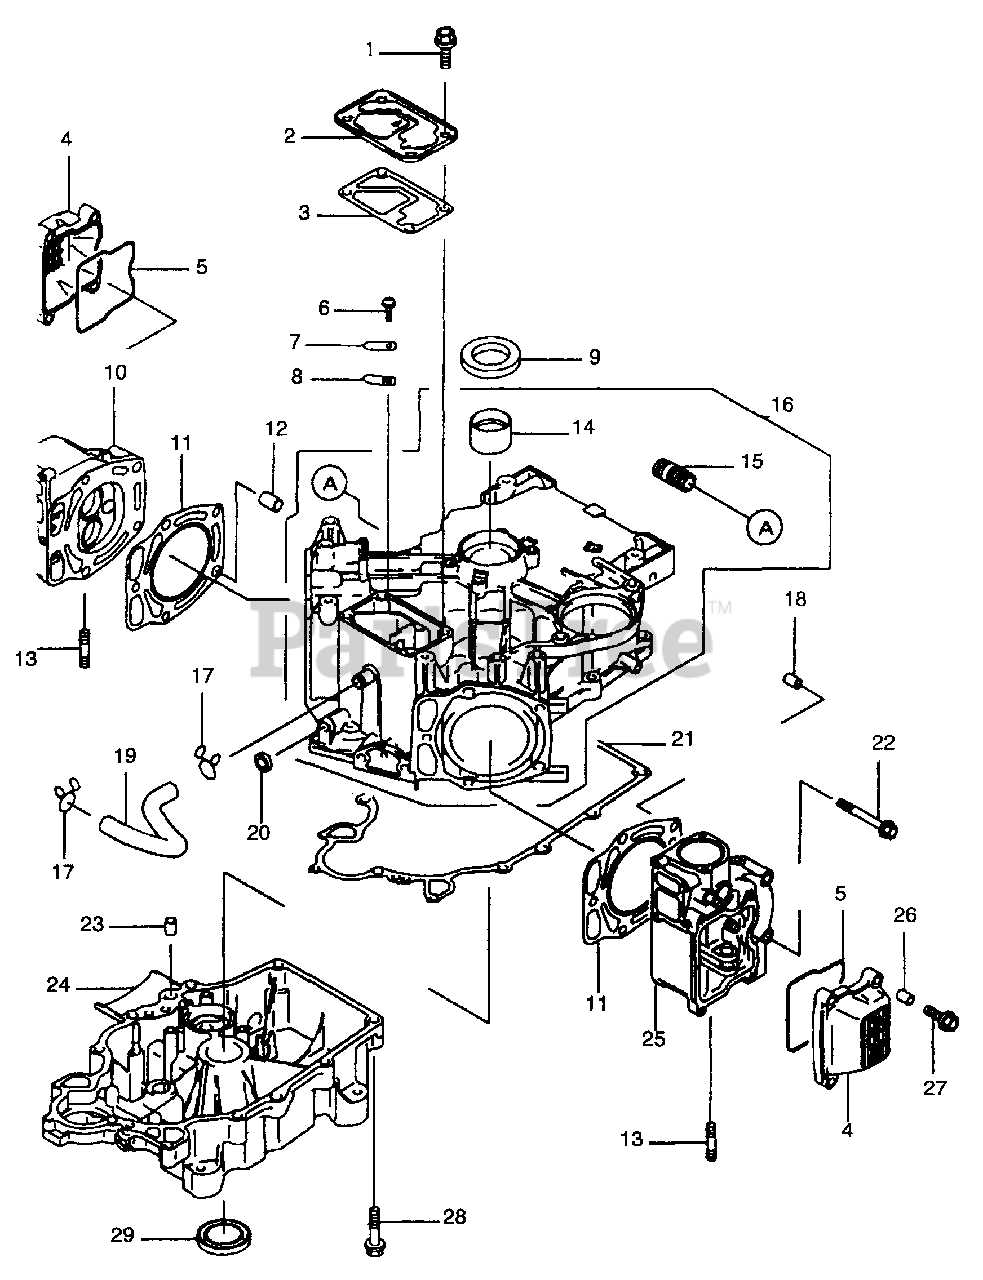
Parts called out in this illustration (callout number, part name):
1	Flanged Bolt
5	Gasket-Rocker Case
9	Oil Seal
10	Head-Comp-Cylinder
14	Plane Bearing
16	Crankcase-Comp
21	Gasket Crankcase Cover
22	Flanged Bolt
24	Cover Crankcase
25	Head Comp Cylinder
27	Flanged Bolt
28	Flanged Bolt
